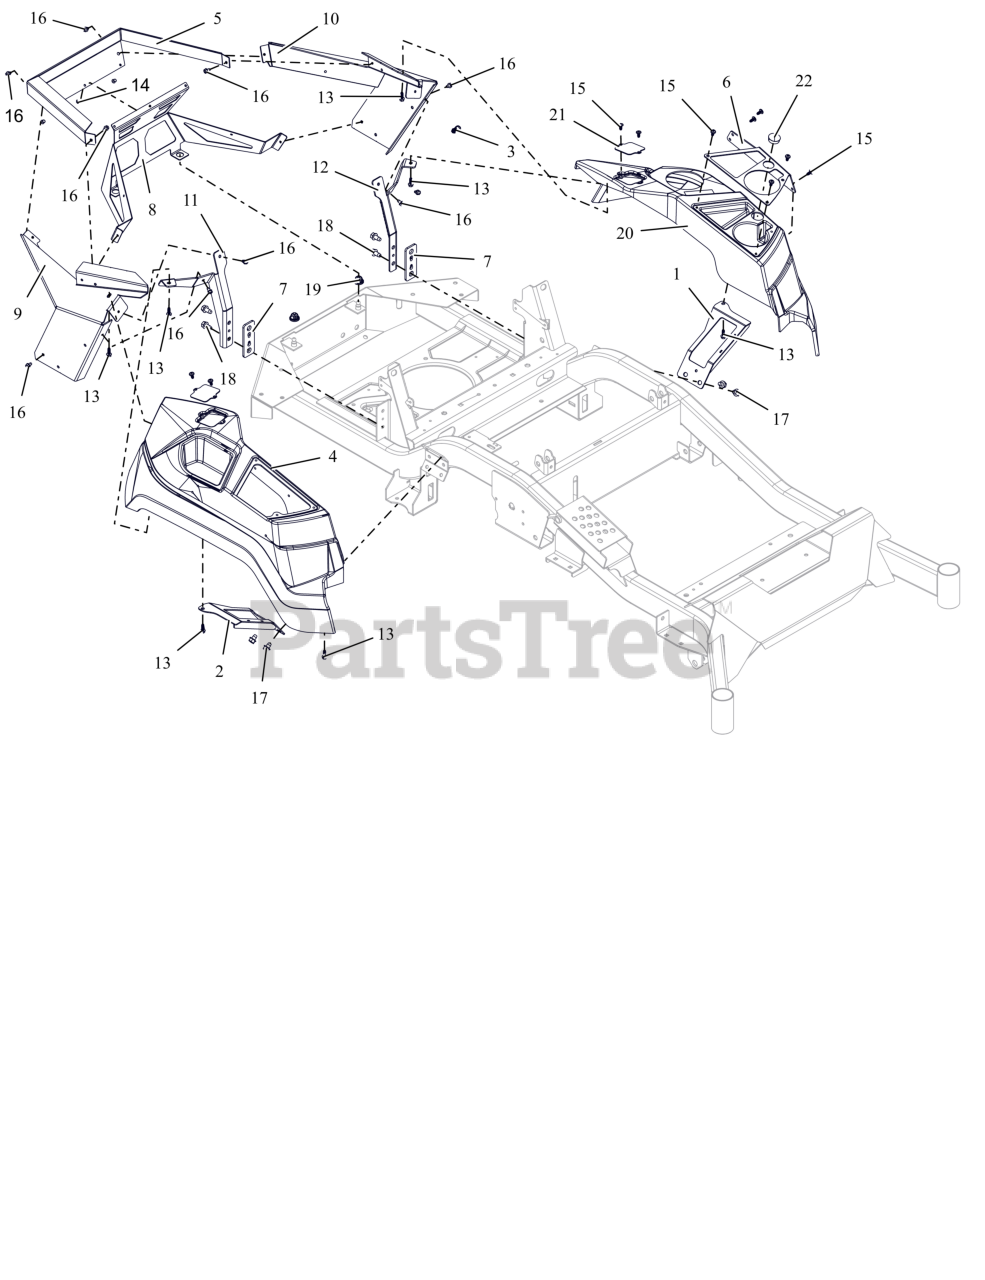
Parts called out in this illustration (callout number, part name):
1	WLDMT, LH FENDER MOUNT
2	WLDMT, RH FENDER MOUNT
3	CLIP, CABLE GUIDE
4	FENDER, RH APEX - 2017
5	GUARD,ENGINE WRAP
6	PLATE-APEX CUP HLDR W/USB(ORG)
7	PLATE, CONTROL PANEL SPACER
8	GUARD, ENGINE
9	PANEL, RH REAR FENDER MOUNT
10	PANEL, LH REAR FENDER MOUNT
11	BRKT, RH FENDER MTG (ORANGE)
12	BRKT, LH FENDER MOUNT (ORANGE)
13	SCR, PLASTITE .25-10X.75 ZCC
14	RVT-POP .187x.250 (#64) BLK
15	SCR-PAN .25-15X.50 6L H/LZB500
16	SCR,TAP .25-20X.375 HWH TR ZCC
17	SCR,TAP .375-16X.50 HWH TR ZCC
18	SCR,TAP .375-16X.75 HWH TR ZCC
19	GROMMET, 10MM BOLLHOFF
20	FENDER, LH APEX
21	PLATE, ROPS HOLE-HD
22	DECAL, ARIENS IKON 52
